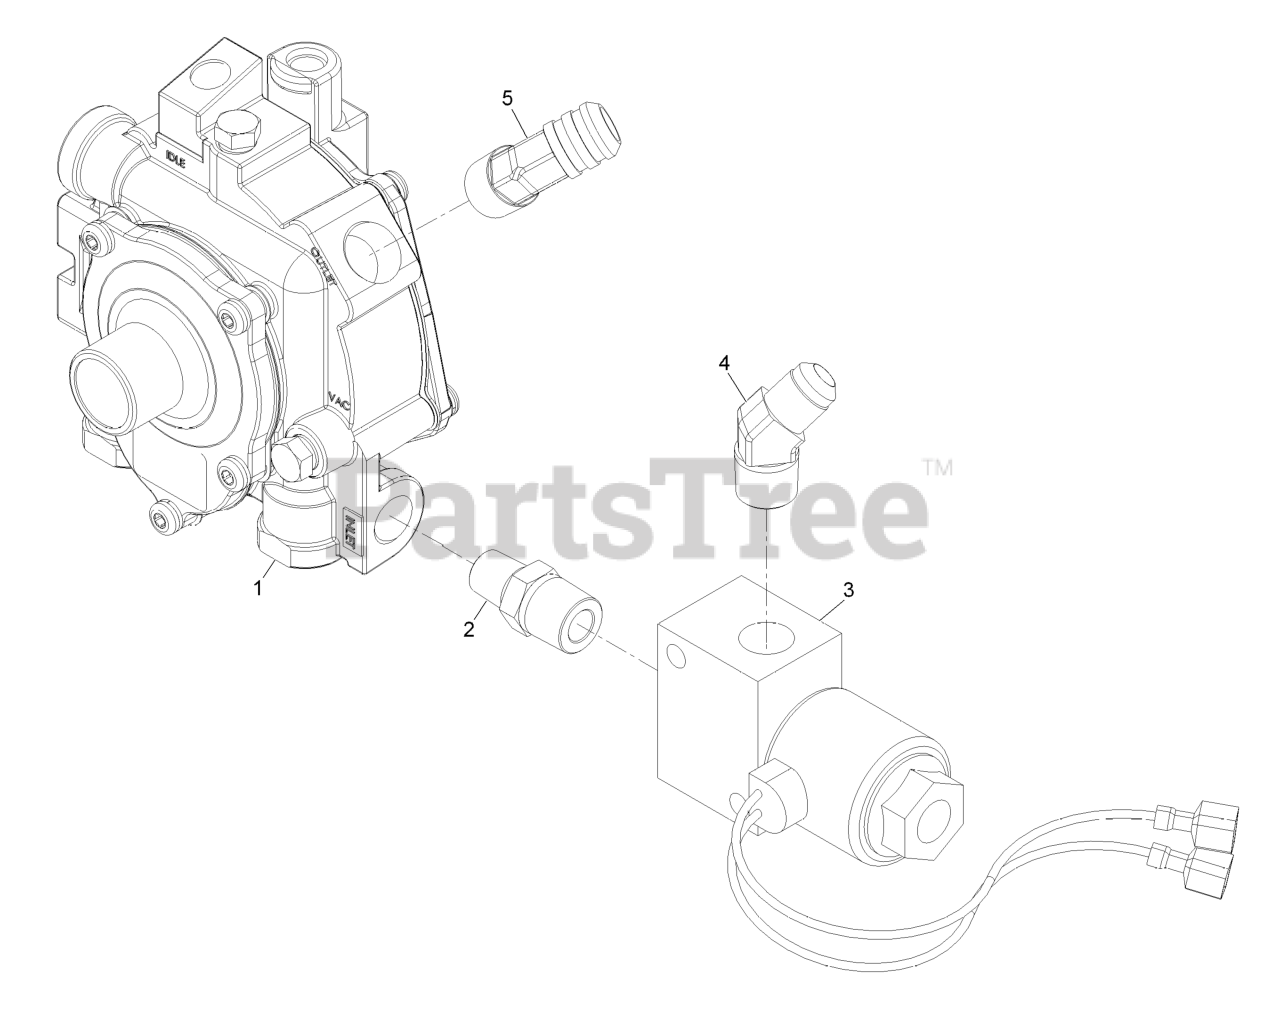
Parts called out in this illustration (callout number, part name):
1	Regulator-Lp, T60
2	COUPLING-PIPE, MALE
3	LPG SOLENOID VALVE ASM
